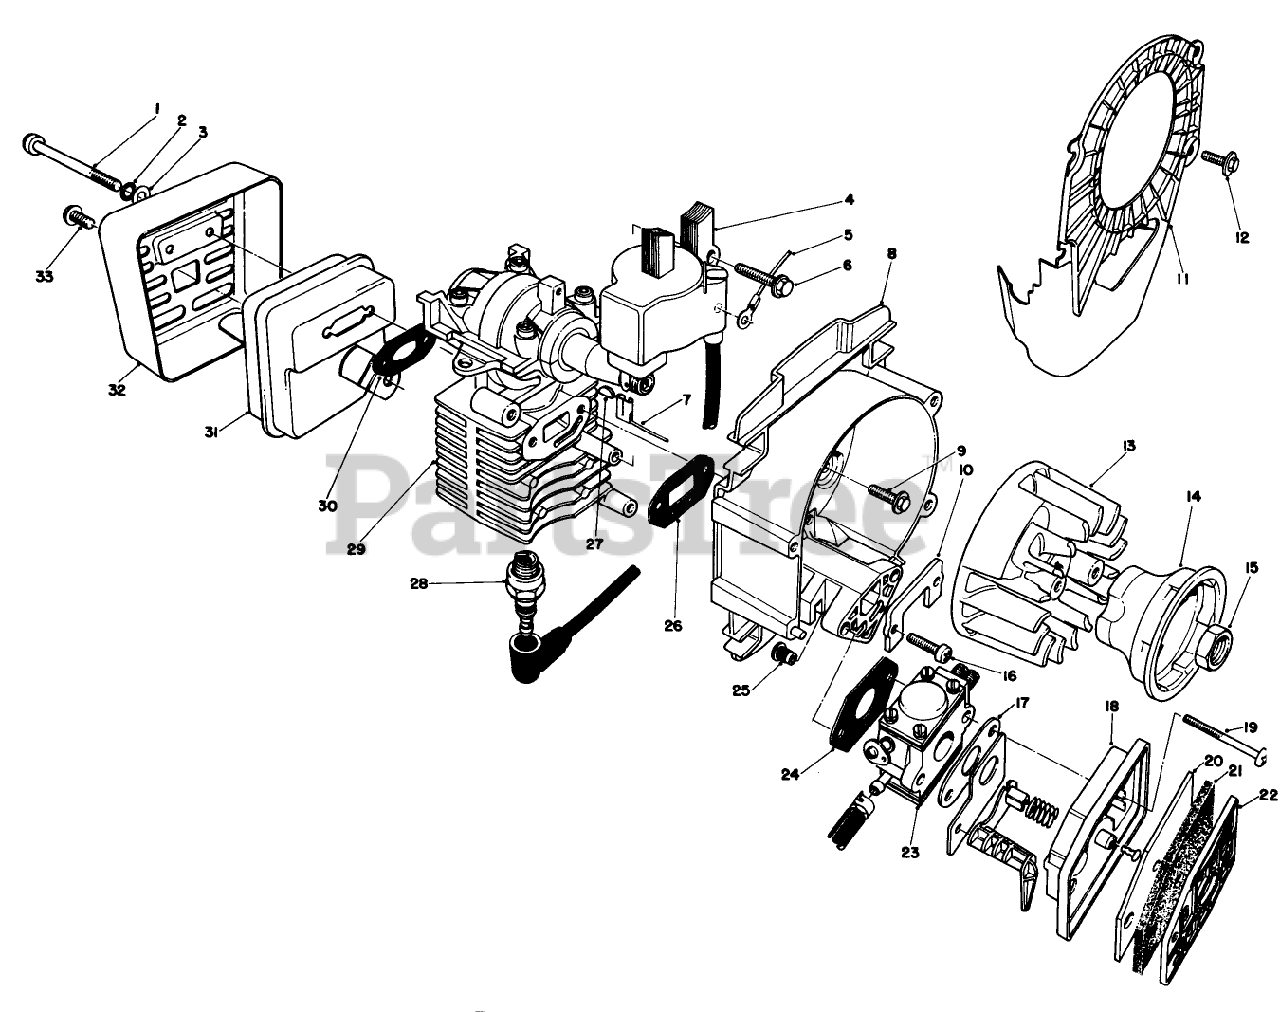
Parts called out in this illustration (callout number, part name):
15	NUT-JAM
21	FILTER FOAM
22	FILTER COVER
23	CARBURETOR ASM
24	CARB. GASKET
26	INTAKE GASKET
30	EXHAUST GASKET
